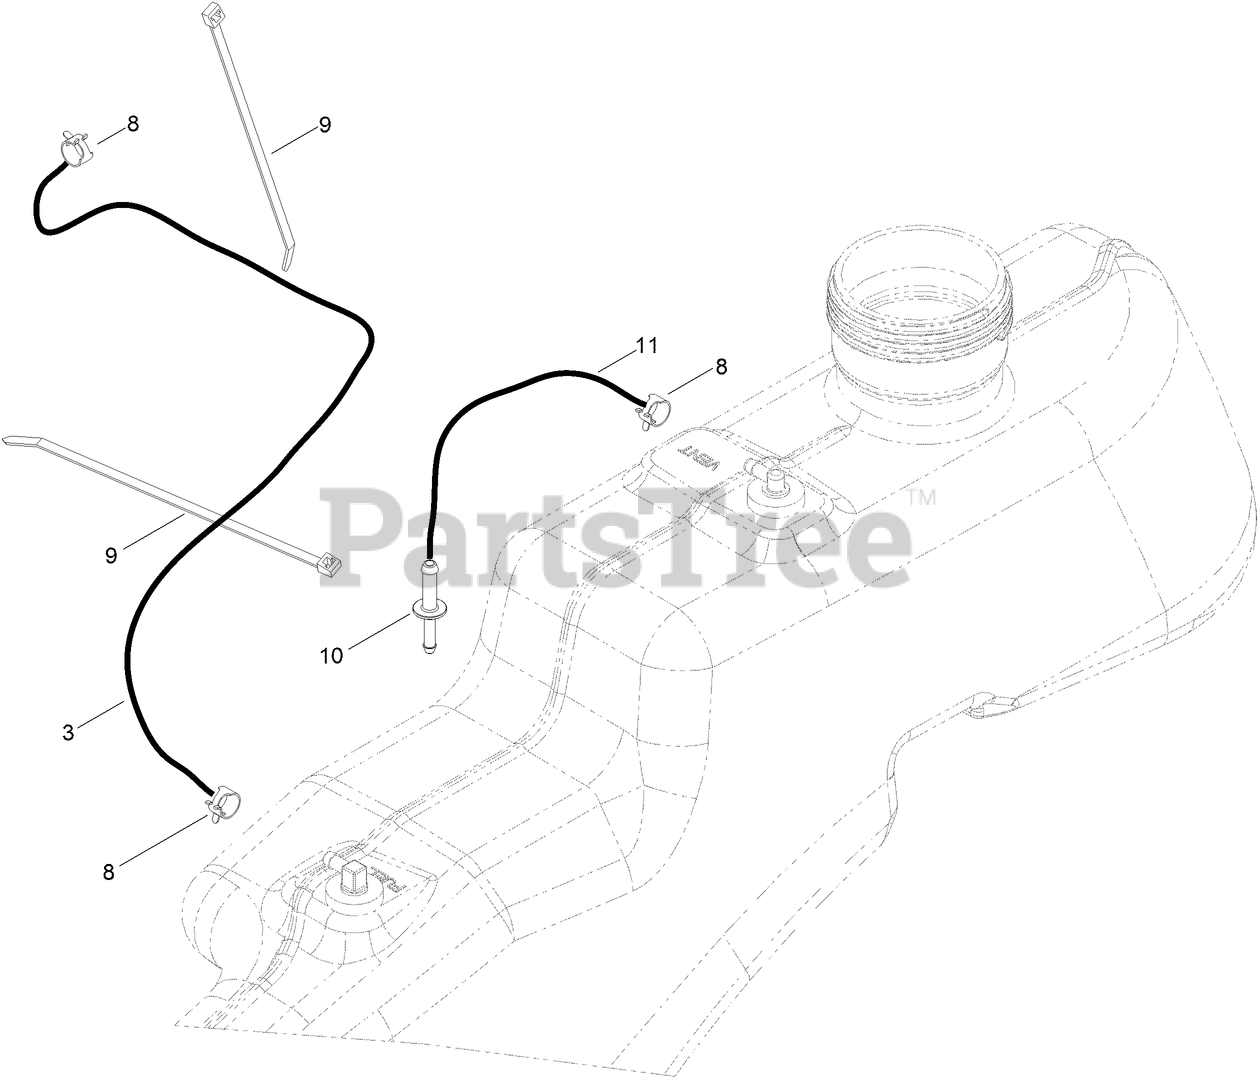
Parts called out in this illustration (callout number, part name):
3	HOSE-FUEL
8	CLAMP-HOSE
9	TIE-CABLE
10	ADAPTOR-ORIFICE
11	HOSE-FUEL
